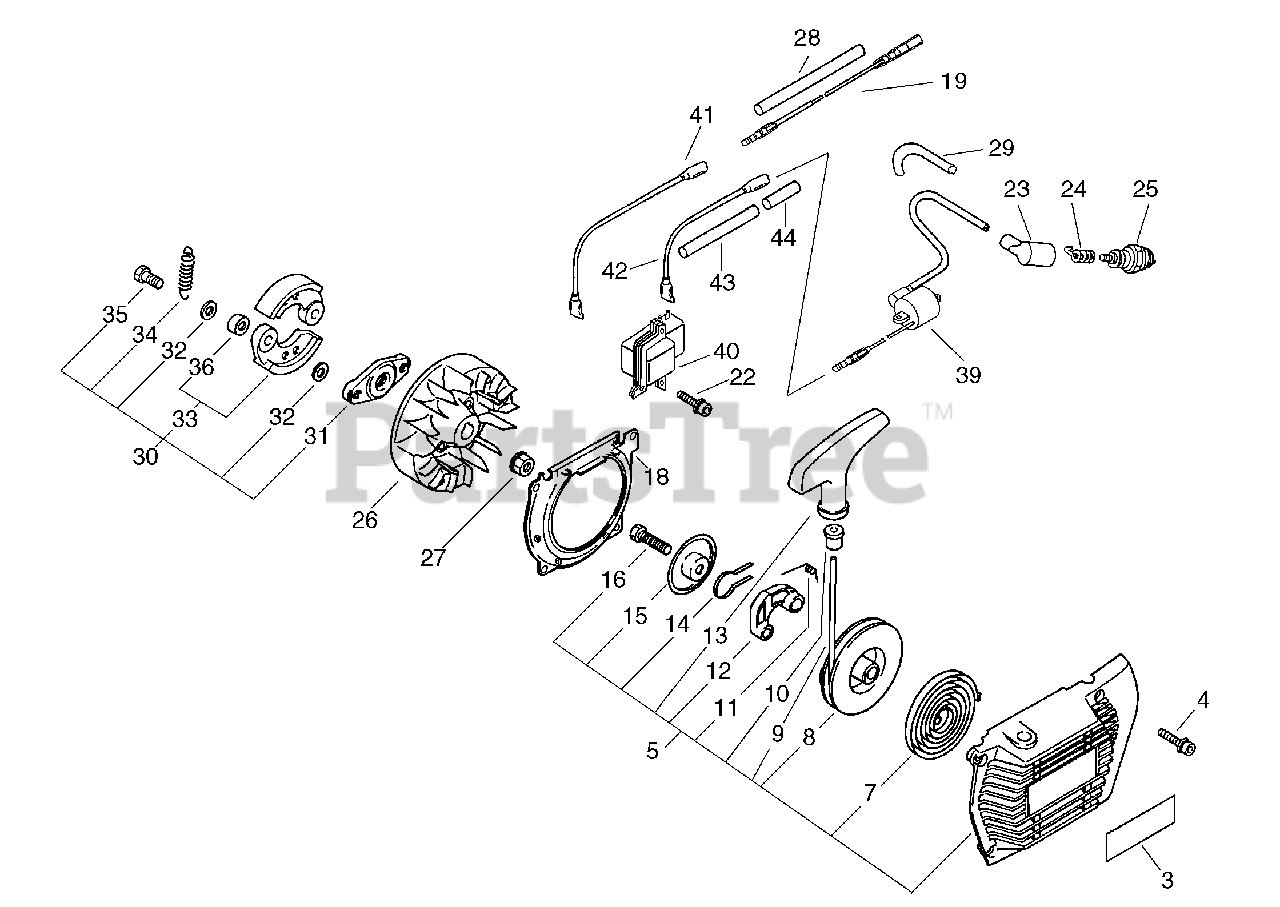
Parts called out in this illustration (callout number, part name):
3	LABEL - ECHO
4	BOLT 5×22
5	STARTER, RECOIL
7	SPRING, REWIND
8	REEL, ROPE
9	ROPE, STARTER
10	GUIDE, ROPE
11	SPRING, RETURN
12	PAWL, STARTER
13	GRIP, STARTER
14	SPRING, FRICTION
15	PLATE, FRICTION
16	BOLT - 6×12
18	COVER, FAN
22	BOLT 5×22
23	CAP, SPARK PLUG
24	TERMINAL, SPARK PLUG
25	SPARK PLUG - BPMR8Y
26	FLYWHEEL
27	NUT, 10 L-H
28	TUBE, INSULATOR 7×8.6×55
30	CLUTCH ASSY
31	HUB, CLUTCH
32	WASHER, CLUTCH
33	SHOE, CLUTCH
34	SPRING, CLUTCH
35	BOLT, CLUTCH
39	COIL, IGNITION
40	COIL, EXCITER
41	LEAD - IGNITION
44	PIPE
